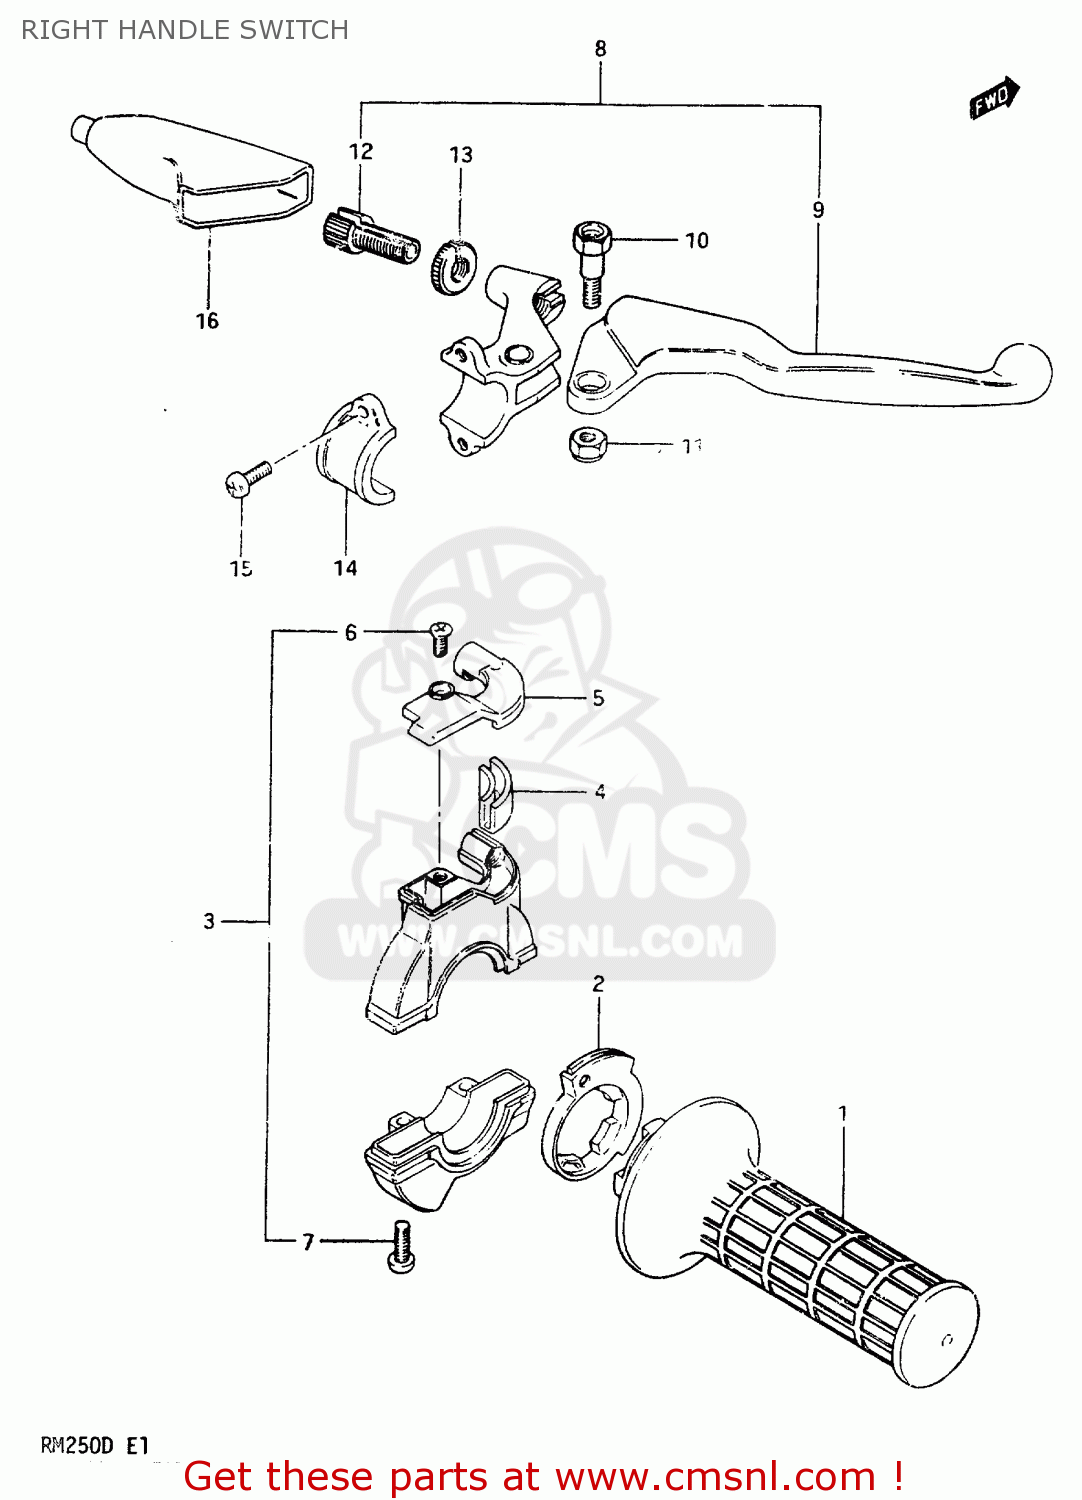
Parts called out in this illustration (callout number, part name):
1	GRIP,THROTTLE
2	ROTOR,THROTTLE GRIP
3	CASE ASSY,THROTTLE
4	GUIDE PIECE,THROTTLE
5	COVER,THROTTLE CASE
6	SCREW 4X10
7	SCREW
8	LEVER ASSEMBLY,BRAKE
9	LEVER,BRAKE
10	BOLT,LEVER
11	NUT 6MM
12	ADJUSTER,CABLE
13	NUT,CABLE ADJUSTER
14	BRACKET,CLUTCH LEVER HOLDER
15	SCREW
16	COVER,CLUTCH LEVER
